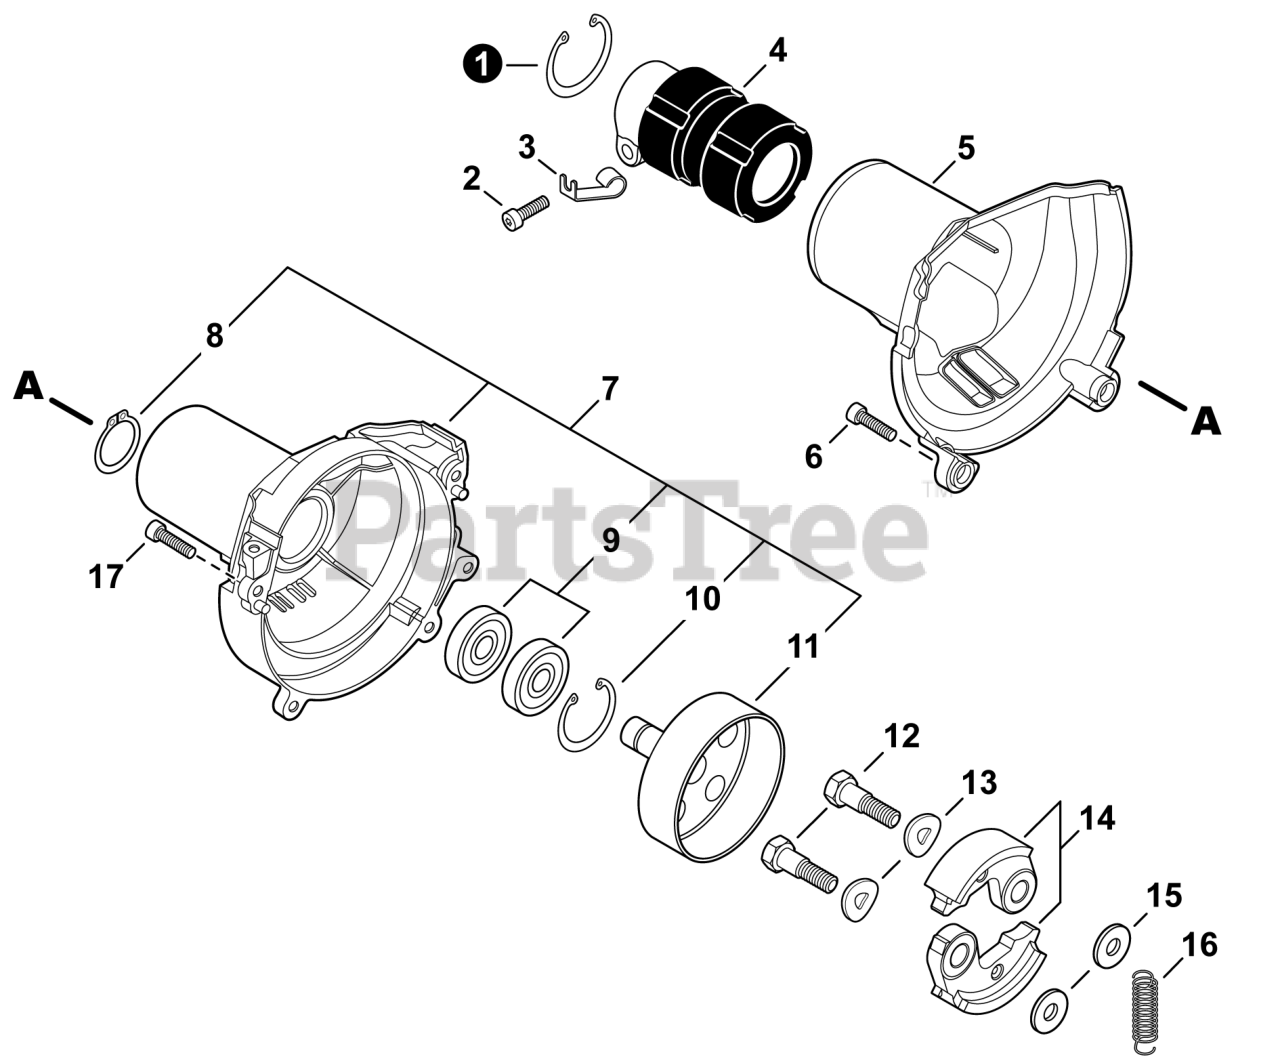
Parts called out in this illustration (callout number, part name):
1	RING, SNAP 42
2	BOLT, TORX 5x25
3	CLIP, CABLE
4	HOLDER, MAIN PIPE
5	PROTECTOR, FAN COVER
6	BOLT, TORX 5x20
7	COVER ASSY, FAN
8	RING, SNAP 12
9	BEARING, BALL 6001
10	RING, SNAP 28
11	DRUM, CLUTCH
12	BOLT, CLUTCH 8x7.9xM6
13	WASHER, SPRING 8.5x16x0.5
14	SHOE, CLUTCH
15	WASHER 6.2x19x1.0
16	SPRING, CLUTCH
17	BOLT, TORX 5x16
